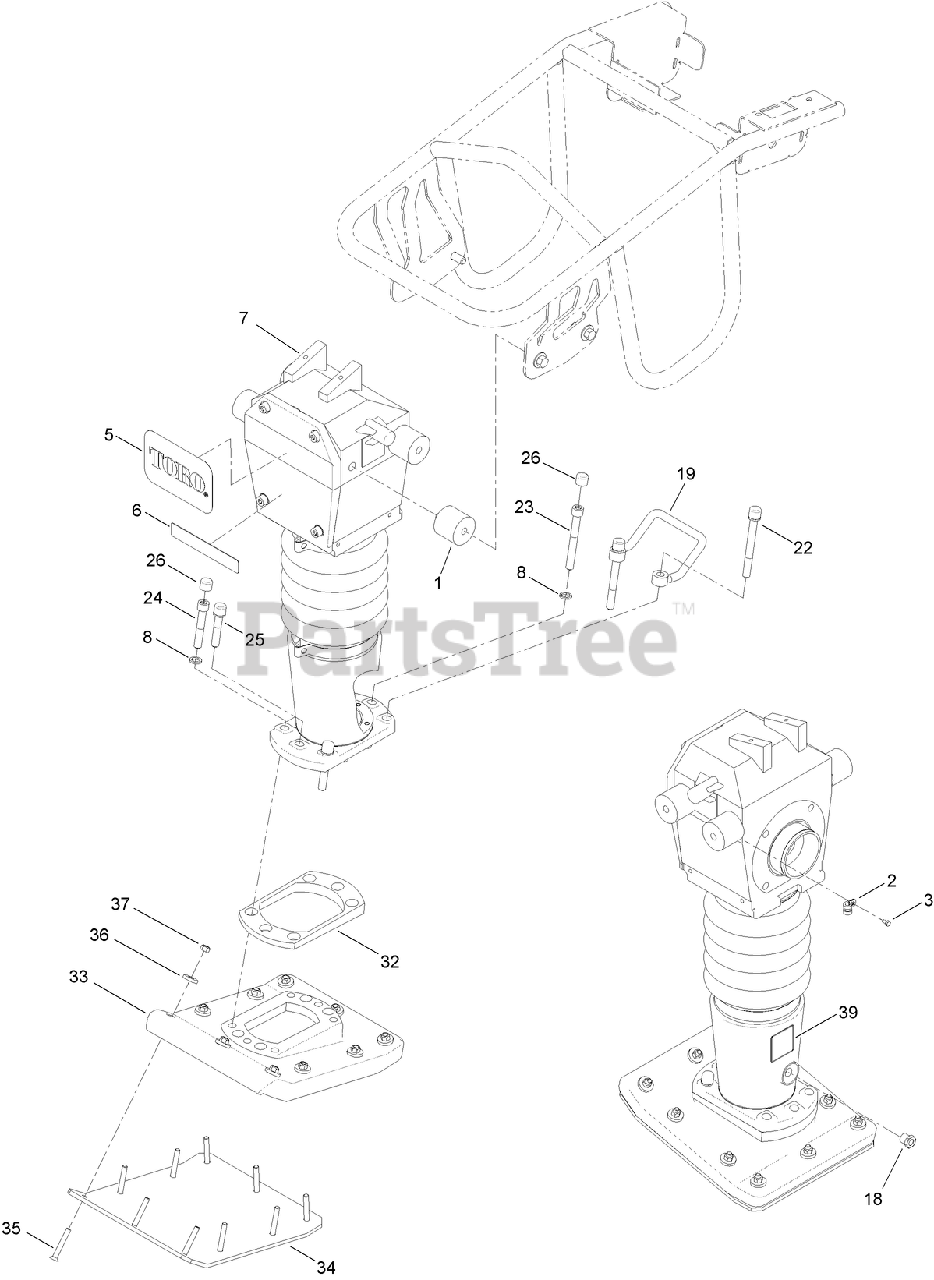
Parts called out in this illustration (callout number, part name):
1	MOUNT-SHOCK
2	CLAMP
3	SCREW-HH
7	RAMMER ASM
8	WASHER-LOCK
18	PLUG-SIGHT, OIL
19	GRIP-LIFT
22	SCREW-HSH
23	SCREW-HSH
24	SCREW-HSH
25	SCREW-HSH
26	CAP-PLASTIC
32	PLATE-SPACER, SHOE
33	SHOE-PLASTIC, MEDIUM/HEAVY
34	PLATE-SHOE
35	SCREW-HSFH
36	WASHER-FLAT
37	NUT-LOCK, NI
39	DECAL-OIL LEVEL
